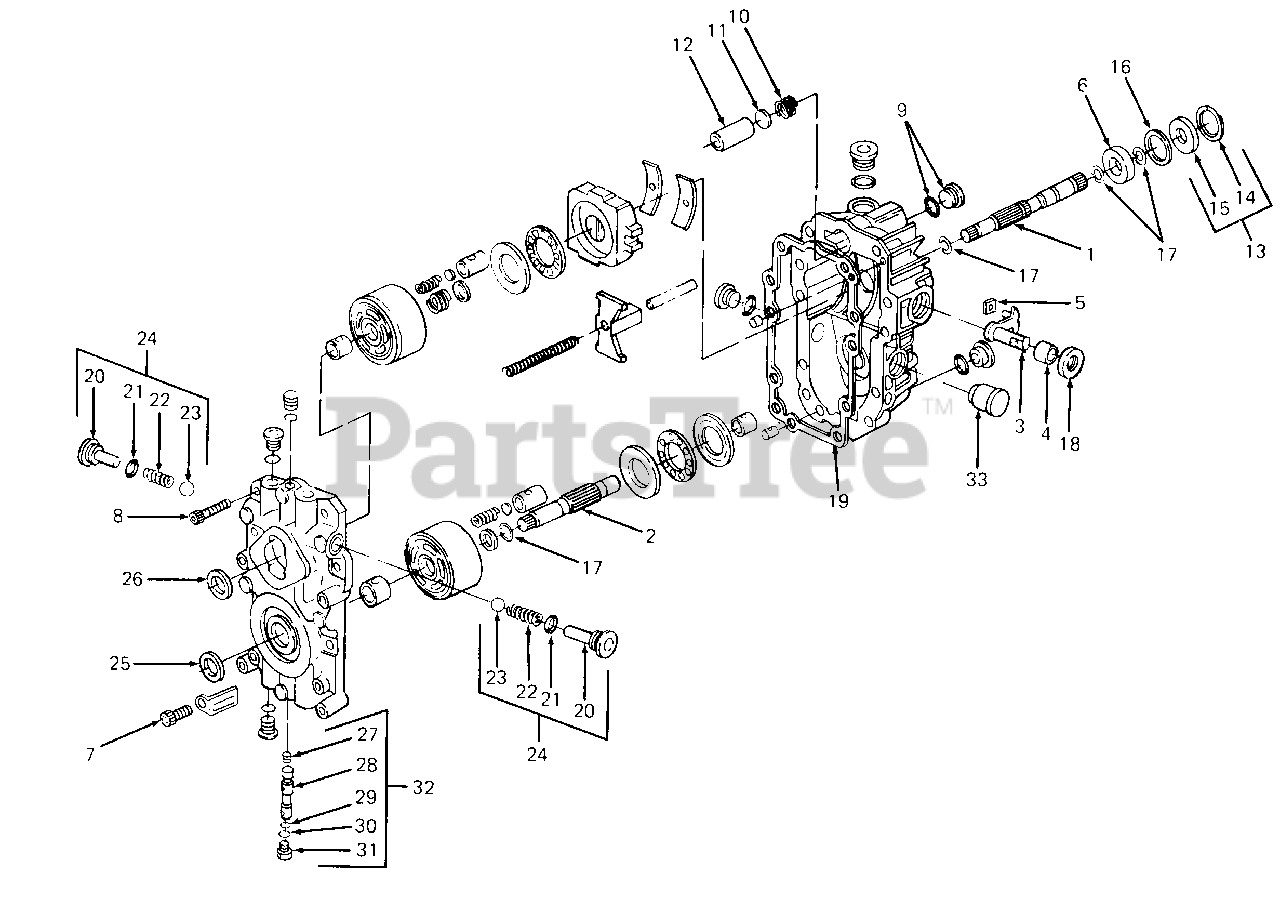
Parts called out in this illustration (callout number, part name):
1	Shaft - Pump
2	Shaft - Motor
3	Arm, Trunnion
4	Bearing, Journal
5	Guide, Slot
6	Bearing, Ball
7	Screw, Socket Head
8	Screw, Socket Head
9	Plug
10	Spring, Filter
11	Washer, Filter
12	Filter
13	Kit, Seal
14	Ring, Retaining
15	Seal, Lip
16	Spacer
17	Ring, Retaining
18	Seal, Lip
19	Gasket
21	O-Ring
24	Kit, Check Valve
25	Seal, Lip
26	Seal, Lip
27	Spring
28	Spool, Bypass
29	O-Ring
30	O-Ring
32	Kit, Bypass Valve
33	Reservoir
